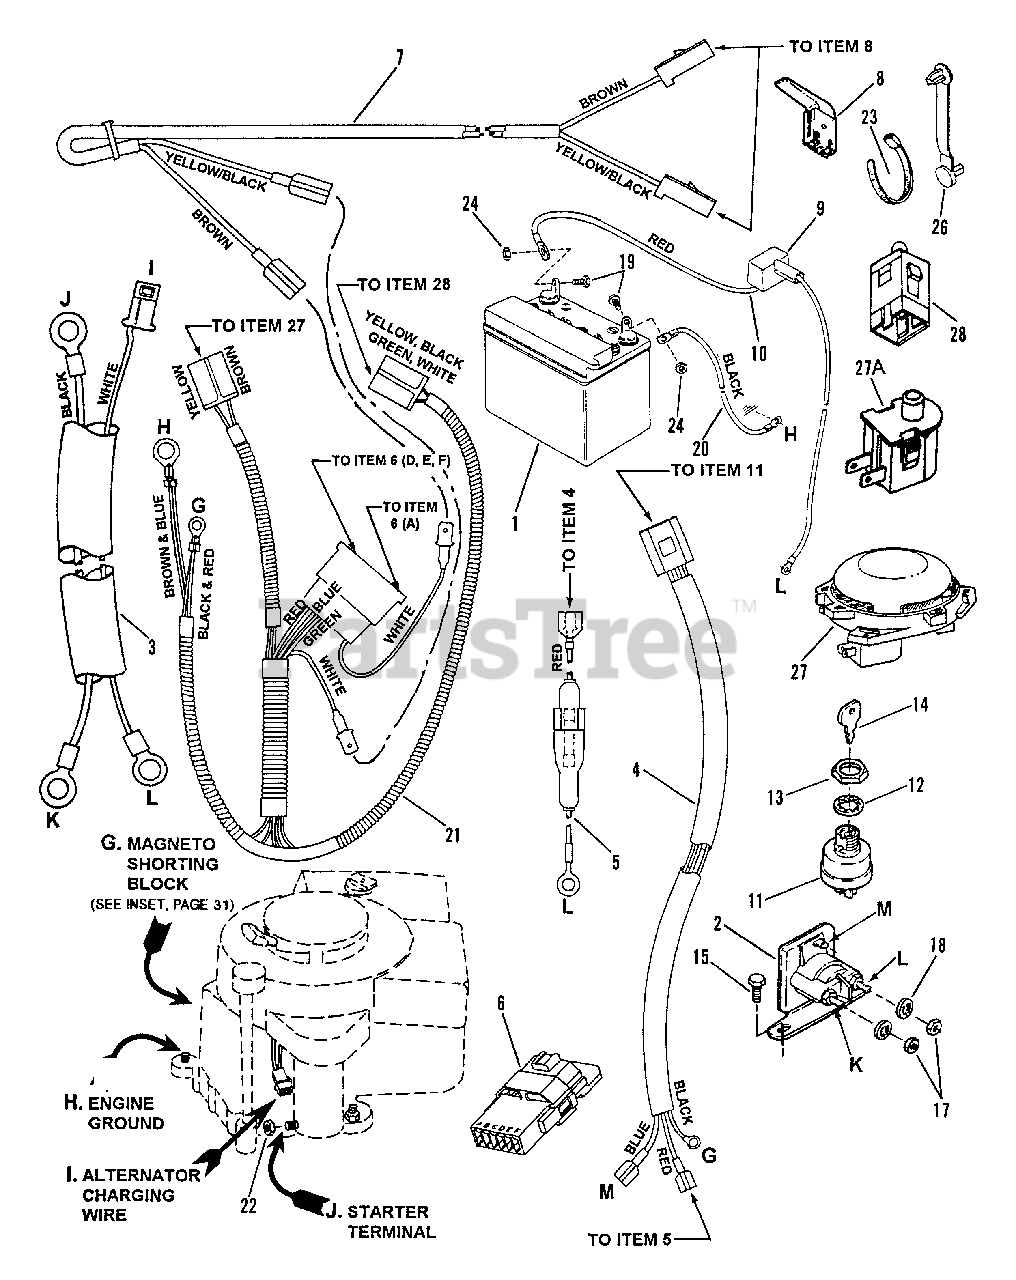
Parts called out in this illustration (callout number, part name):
1	KIT, 12V Dry Charge Battery
2	SOLENOID
3	HARNESS, Starter Wiring
4	HARNESS, Ignition Wiring
5	HOLDER, Fuse
6	INTERLOCK Module
7	HARNESS, (Deck Interlock Wiring)
8	SWITCH, Deck Interlock
9	COVER, Battery Cable
10	CABLE, Positive (Red)
11	SWITCH, Ignition (Includes keys #11138)
12	WASHER, 5/8 Internal Tooth Lock
13	NUT, 5/8-32 Hex
14	KEY, Switch
15	SCREW, 1/4-20 x 1/2" Self-Tapping
17	NUT, 1/4-20 Hex
18	WASHER, 1/4 Internal Tooth Lock
19	SCREW, 1/4-20 x 5/8" Hex Head Cap
20	CABLE, Negative
21	HARNESS, Operator Presence Control Wire
22	NUT, 1/4-20 Hex
23	TIE, 7" Long Cable
24	NUT, 1/4-20 Hex Lock
26	TIE, 2" Long Cable
27	SWITCH, Seat
27A	SWITCH, Seat
28	SWITCH, Operator Presence Control Traction
